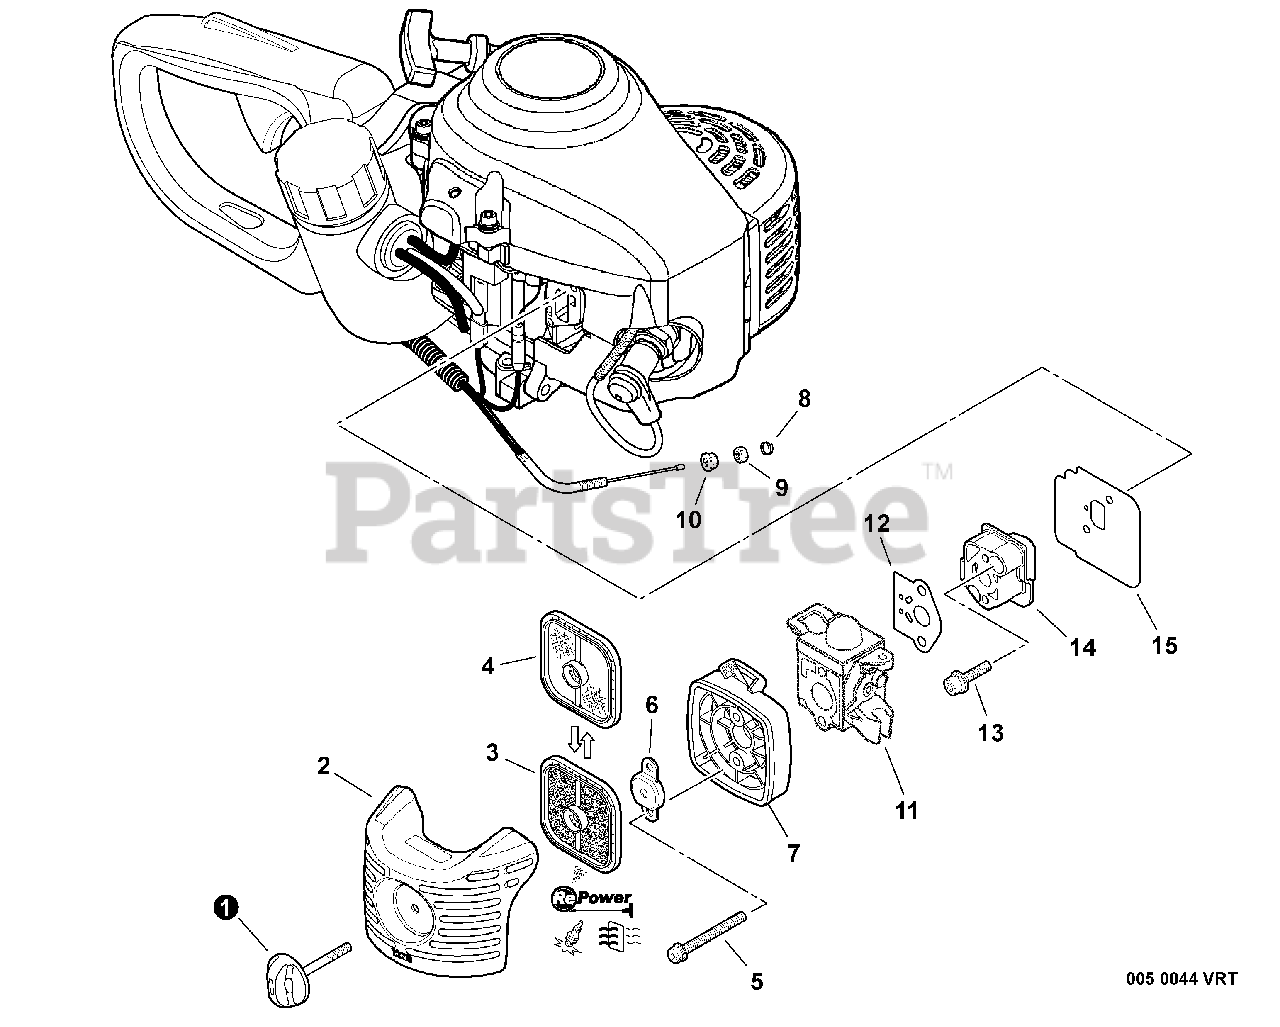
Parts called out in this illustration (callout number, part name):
1	THUMBSCREW
2	COVER, AIR FILTER
3	FILTER, AIR - DOUBLE LAYER
4	FILTER, AIR - SINGLE LAYER
5	SCREW 5×65
6	PLATE, PREVENT
7	CASE ASSY, AIR FILTER
10	NUT, FLANGE M6
11	CARBURETOR
12	GASKET, INTAKE
13	BOLT 5×25
14	INSULATOR, INTAKE
15	HEAT SHIELD, INTAKE
TU	TUNE-UP KIT - REPOWER
FF	FILTER KIT - REPOWER
